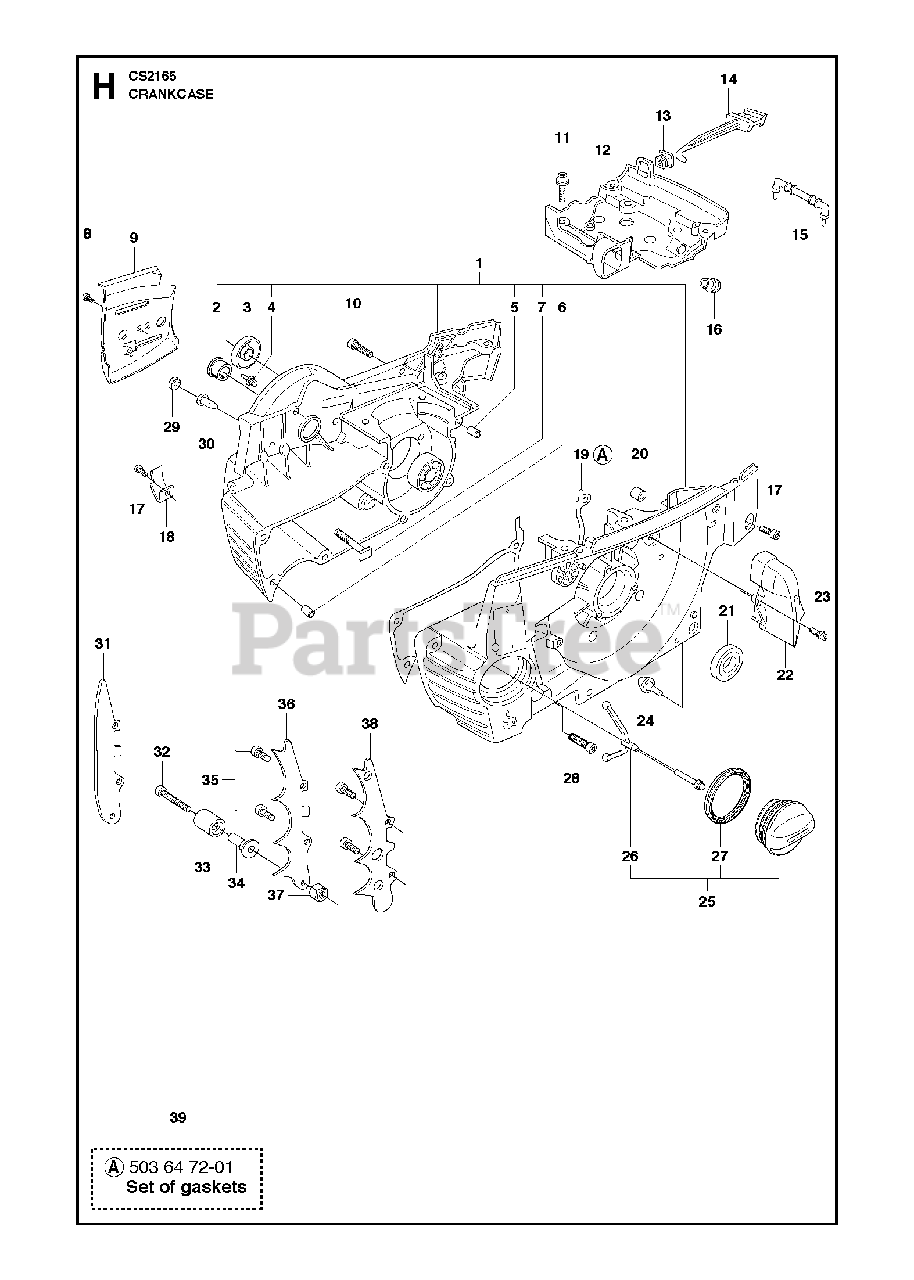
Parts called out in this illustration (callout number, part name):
1	CRANKCASE ASSY
2	BUSHING
3	SEAL
4	PIN
5	SLEEVE
6	SLEEVE
7	BOLT
11	SCREW
12	BASE
14	CHOKE CONTROL
15	SPACER
17	SCREW IHSCM
18	CHAIN CATCHER
19	GASKET
20	PROTECTOR
21	SEAL RING
23	SCREW
25	TANK CAP
26	HOLDER
27	SEALING
29	PLUG
30	VALVE-CHECK (DUCKBILL)
32	SCREW IHSCFM
36	FELLING DOG
38	FELLING DOG
39	GASKET SET
